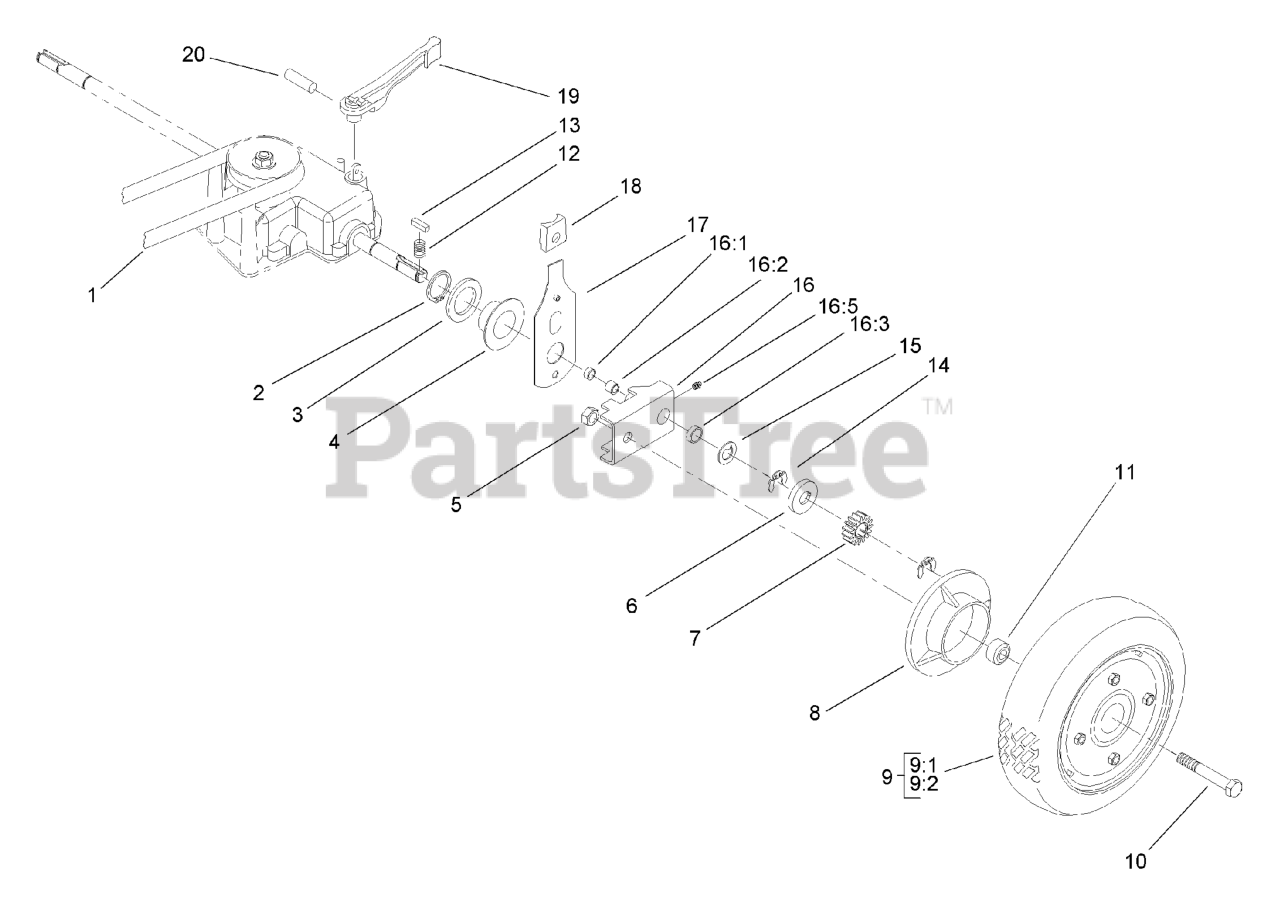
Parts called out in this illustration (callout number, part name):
1	V-BELT
2	RING-RETAINING
4	CAP-END
5	NUT-LOCK, CONE
6	WASHER-THRUST, OUTER
7	GEAR-PINION
8	COVER-WHEEL
9:2	Wheel Asm
10	SCREW-HH
11	SPACER-COVER, WHEEL
12	SPRING-COMPRESSION
14	RING-RETAINING
15	WASHER-THRUST, OUTER
16	PIVOT ARM ASM
16:1	SEAL-OIL
16:3	BEARING-WHEEL
17	REAR SPRING ARM ASM
18	KNOB-ARM
19	LEVER-SHIFT
20	PIN-SPRING
